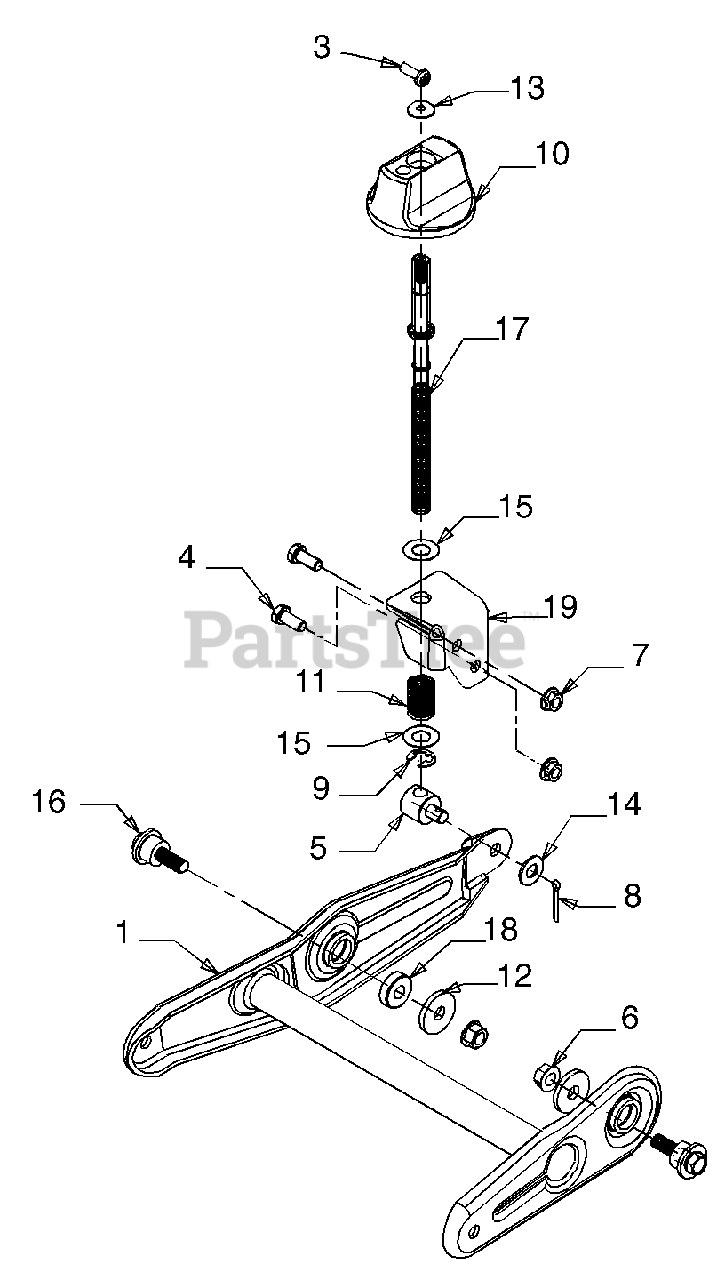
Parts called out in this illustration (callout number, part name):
1	Bracket Ass'y, Wheel Pivot
3	Screw, Pan Hd Mach, 1/4-20 x .75
4	Screw, Hex Cap, 5/16-18 x .75 GR5
5	Ferrule, Adjustment
6	Nut, Hex Flange Lock, 3/8-16
7	Nut, Hex Flange Lock, 5/16-18
8	Pin, Cotter, 1/8 x 1.0
9	E-Ring, .50 Dia
10	Knob
11	Spring, Compression
12	Washer, Flat, .406 x 1-1/4
13	Washer, Bell, .265 x .75 x .062
14	Washer, Flat, .406 x .875 x .059
15	Washer, Flat, .508 x 1.0 x .020
16	Shoulder Bolt, .75 x .43: 3/8-16
17	Rod, Height Adjustment
18	Spacer, .380 ID x 1.0 OD x .32 Lg
19	Bracket, Height Adj
